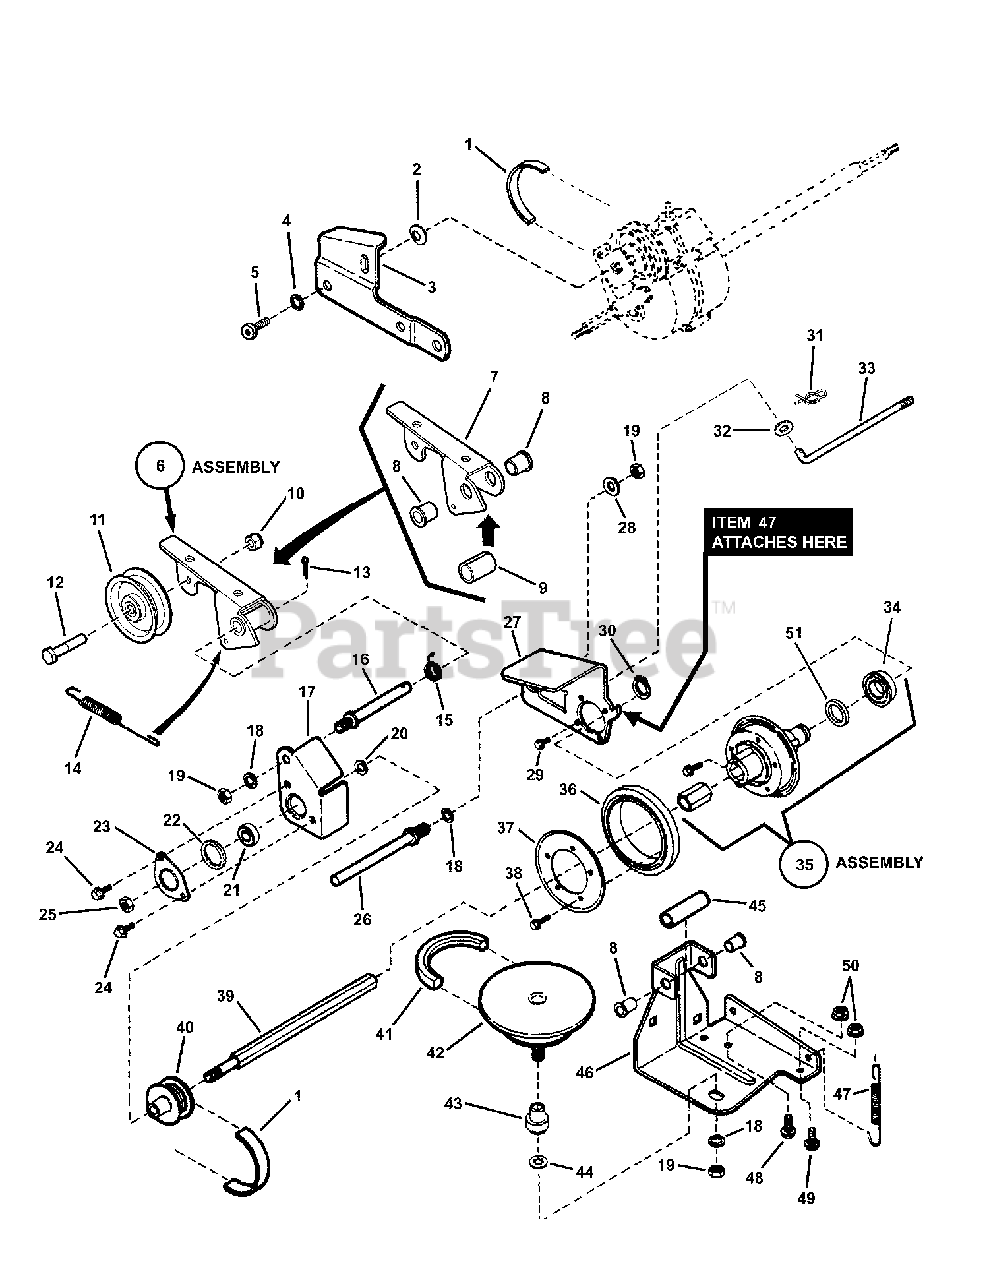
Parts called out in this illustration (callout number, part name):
1	BELT, Poly-V
2	WASHER, 44 x .78 x .025 Curved
3	LINK, Differential
4	WASHER, 5/16" Internal Tooth Lock
5	SCREW, 5/16-18 x 1/2" Pan Head Self-Tap (Torx)
6	ASSEMBLY, Idler Arm, Bushing & Spacer
7	ARM, Clutch Idler
8	BUSHING, Flange (Powdered Metal)
9	SPACER, Idler Arm
10	NUT, 1/4-28 Hex Top Lock
11	PULLEY, Idler
12	SCREW, 1/4-28 x 1-3/8" Hex Head Cap, GR 5
13	COTTER PIN, 3/32 x 1/2"
14	SPRING, Clutch- 21S
15	SPRING, Idler- Torsion
16	STUD, Idler (3/8-24 thread)
17	HOLDER, Bearing (Inner Half)
18	WASHER, 3/8" Internal Tooth Lock
19	NUT, 3/8-24 Hex
20	WASHER, 3/8" Flat
21	BALL BEARING, Spherical O.D., .38 I.D.
22	O-RING
23	HOLDER, Bearing (Outer Half)
24	SCREW, 1/4-20 x 1/2" Hex Flange Self-Tap
25	NUT, 3/8-24 Hex Center Lock, GR 5
26	GUIDE, Thrust Plate (3/8-24 thread)
27	THRUST PLATE, Short
28	WASHER, 3/8" Flat
29	SCREW, #10-32 x 1/4" Self-Tap Machine
30	RETAINING RING, .625 External
31	COTTER PIN, .06 x .50
32	WASHER, .28 x .63 x .06 Flat
33	LINK, Transfer (1/4-28 thread)
34	BALL BEARING, 3/4" Bore- Commercial
35	* KIT, Bushing & Hub Assembly
36	DRIVEN RING, 21P
37	PLATE, Ring Retaining
38	SCREW, #10-24 x 1/2" Self-Tap Machine
39	SHAFT, Hex (3/8-24 thread, one end)
40	PULLEY, Poly-V (2.00" O. D.)
41	BELT, Engine Drive (Stretch)
42	ASSEMBLY, Steel Drive Disc
43	BUSHING, Powdered Metal
44	RETAINER, 5/16" Bolt
45	SPACER, .500 x .65 x 1.75
46	BRACKET, Deck, P21S
47	SPRING, Wheel Drive
48	BOLT, 5/16-18 x 1/2", Short Neck Carriage, GR 5
49	BOLT, 5/16-18 x 5/8" Short Neck Carriage, GR 5
50	NUT, 5/16-18 Hex Flange Lock GR 5
51	WASHER, 3/4" Shim
